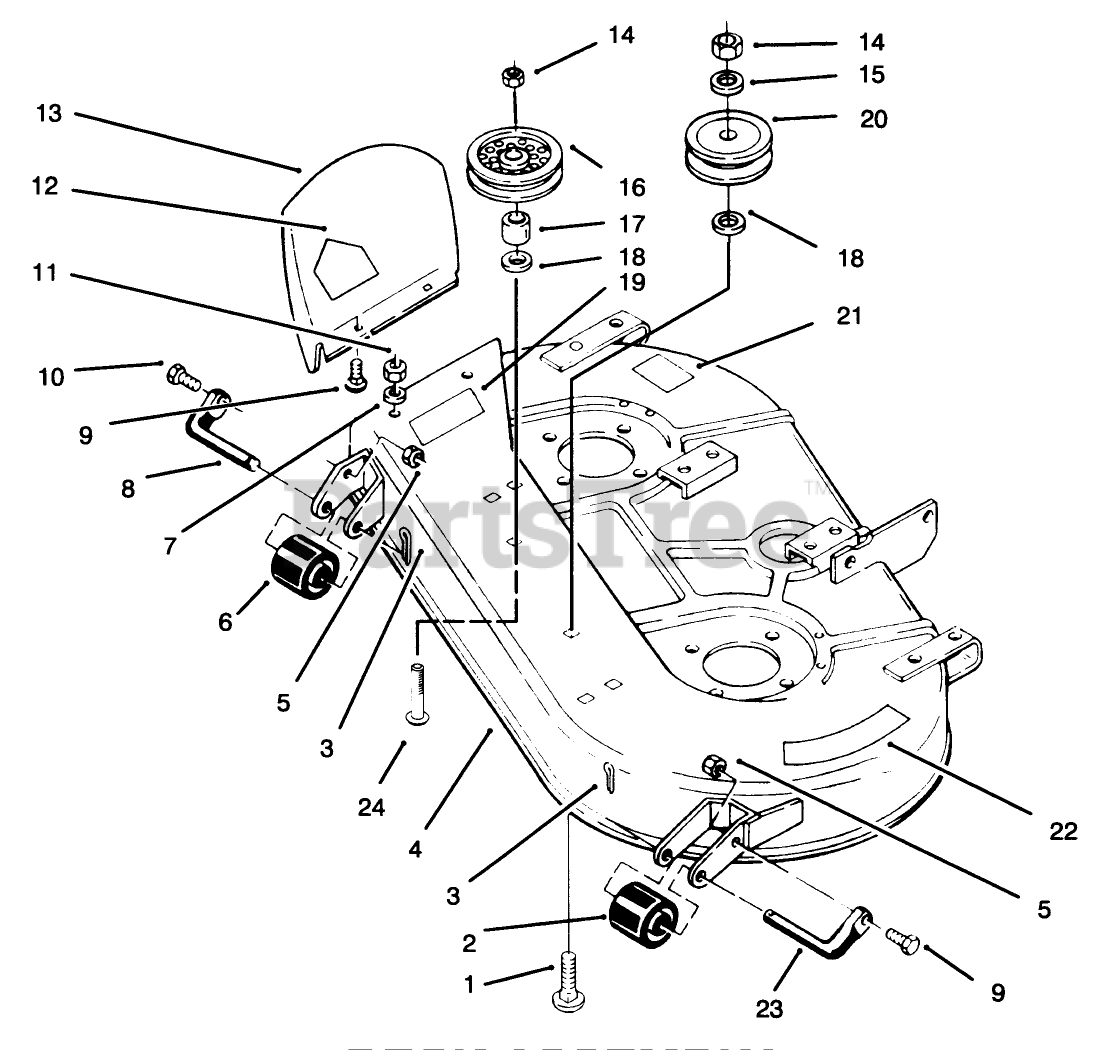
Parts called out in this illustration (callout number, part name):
1	SCREW-CARR
2	ROLLER
3	PIN-COTTER
4	Deck-Mower (Incl. Ref. #19 & 22)
5	NUT-LOCK, NI
6	Roller
7	WASHER-PLAIN
8	ROLLER-SHAFT
9	BOLT-CARR
10	SCREW-HH
11	NUT-LOCK, NI
12	DECAL-DANGER
13	Extension-Chute (Incl. Ref. #12)
14	NUT-LOCK, NI
15	WASHER-FLAT
16	PULLEY-FLAT IDLER B
17	SPACER
18	WASHER-FLAT
19	DECAL-DANGER
20	PULLEY-IDLER
21	DECAL BELT INSTALLAT
22	DECAL-DANGER
23	SHAFT-ROLLER
24	SCREW-CARR
